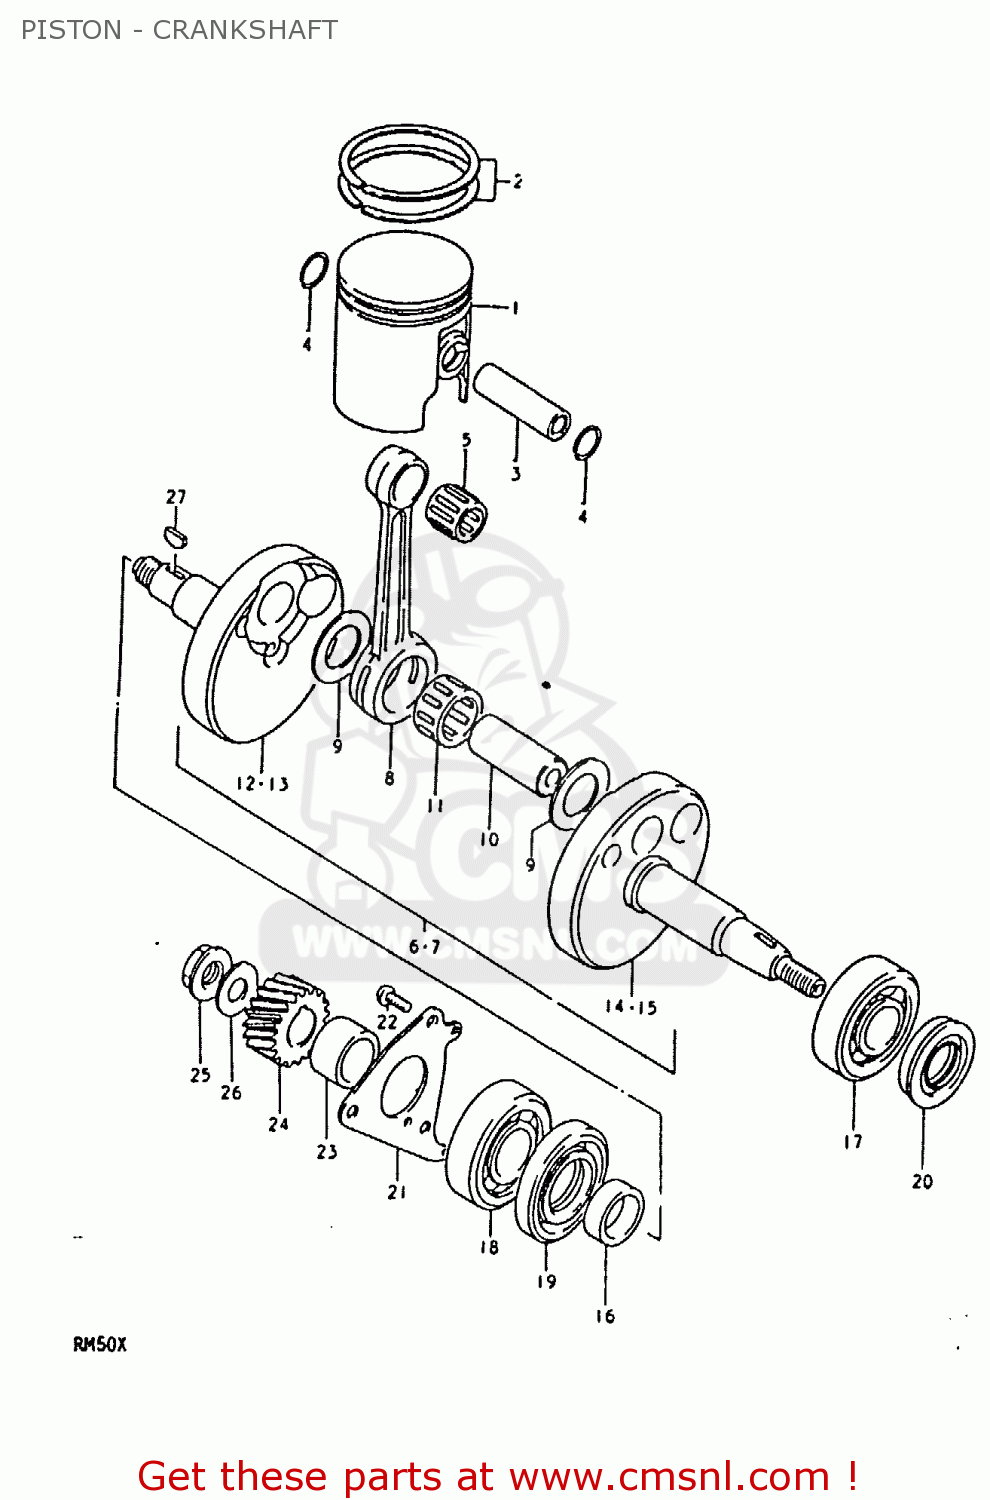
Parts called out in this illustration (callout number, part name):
1	PISTON
2	RING SET,PISTON
3	PIN,PISTON
4	RING,SNAP
5	BEARING
6	CRANKSHAFT ASSEMBLY
7	CRANKSHAFT ASSEMBLY
8	CONNECTING ROD
9	WASHER(16X29X1)
10	PIN,CRANK
11	BEARING
12	CRANKSHAFT,RIGHT
13	CRANKSHAFT
14	CRANKSHAFT,LEFT
15	CRANKSHAFT,LEFT
16	SPACER(20X26X9)
17	BEARING
18	BEARING
19	OIL SEAL
20	OIL SEAL
21	RETAINER,CRANKSHAFT BEARING,R
22	SCREW 6X12
23	SPACER(20X26X14)
24	GEAR,PRIMARY DRIVE NO.19
25	NUT
26	WASHER
27	KEY
